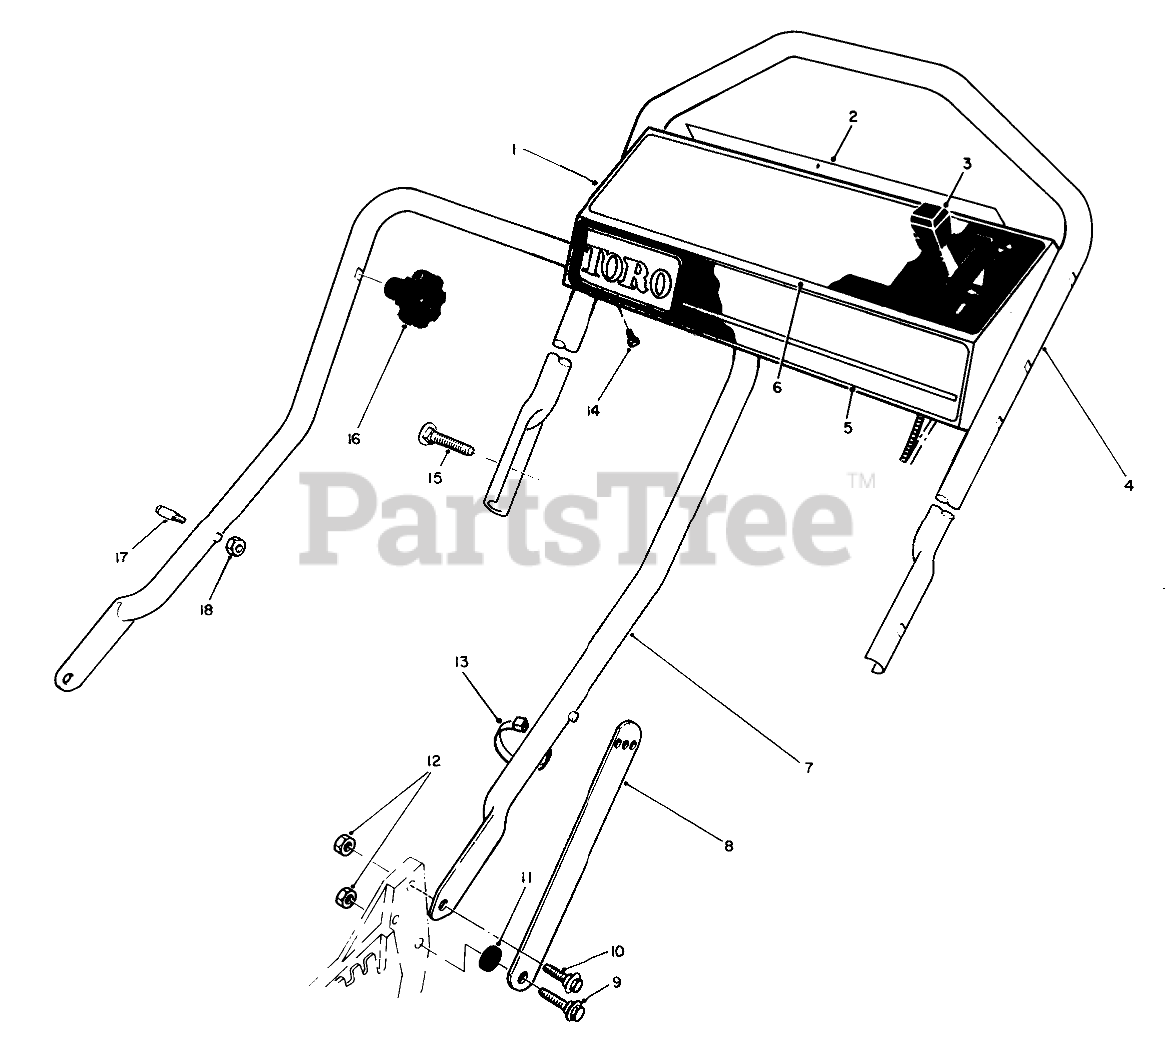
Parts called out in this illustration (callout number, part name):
1	Panel-Control (Incl. Ref. #2, 5, & 6)
2	DECAL - PANEL, REAR
3	THROTTLE CONTROL
4	Handle-Upper
5	DECAL - TORO PANEL
6	DECAL - INSTRUCTION
7	LOWER HANDLE ASM
8	Handle Latch
9	SCREW-SHOULDER
10	SCREW-SHOULDER
11	SPACER
12	NUT-LOCK, NI
13	TIE-CABLE
14	SCREW-HWHTF
15	5/16-18 X 2 HNDLE SCREW
17	HANDLE PIN
18	NUT-LOCK, NI
